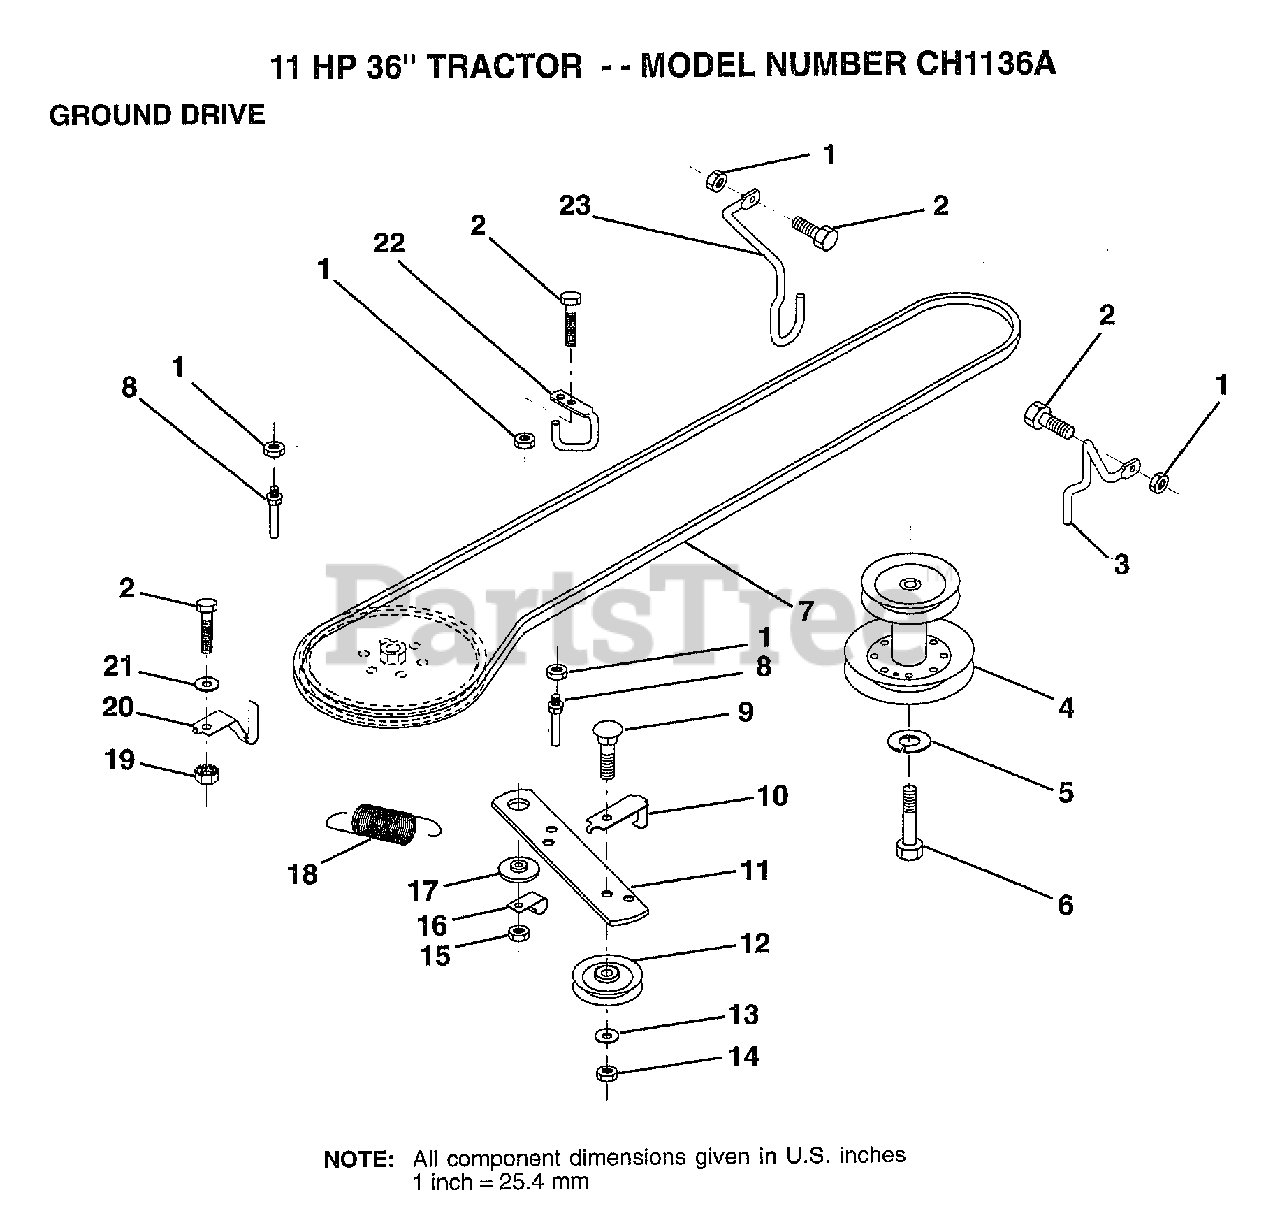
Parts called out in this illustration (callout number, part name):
1	NUT
2	BOLT
3	KEEPER RH
4	PULLEY.ENGINE.LR
5	LOCKWASHER
6	HEX BOLT
7	BELT
8	"KEEPER,DRIVE BELT"
9	BOLT
10	"KEEP,IDLER DR BEL"
11	ARM IDLER CLUT GD
12	PULLEY.IDLER.FLAT
13	WASHER
14	LOCKNUT
15	NUT
16	"CLIP,INSULATOR"
17	SPACER RETAINER
20	KEEPER.BELT.T/A
21	WASHER
22	"KEEPER,FRA DR BEL"
23	KEEPER MOWER LH
